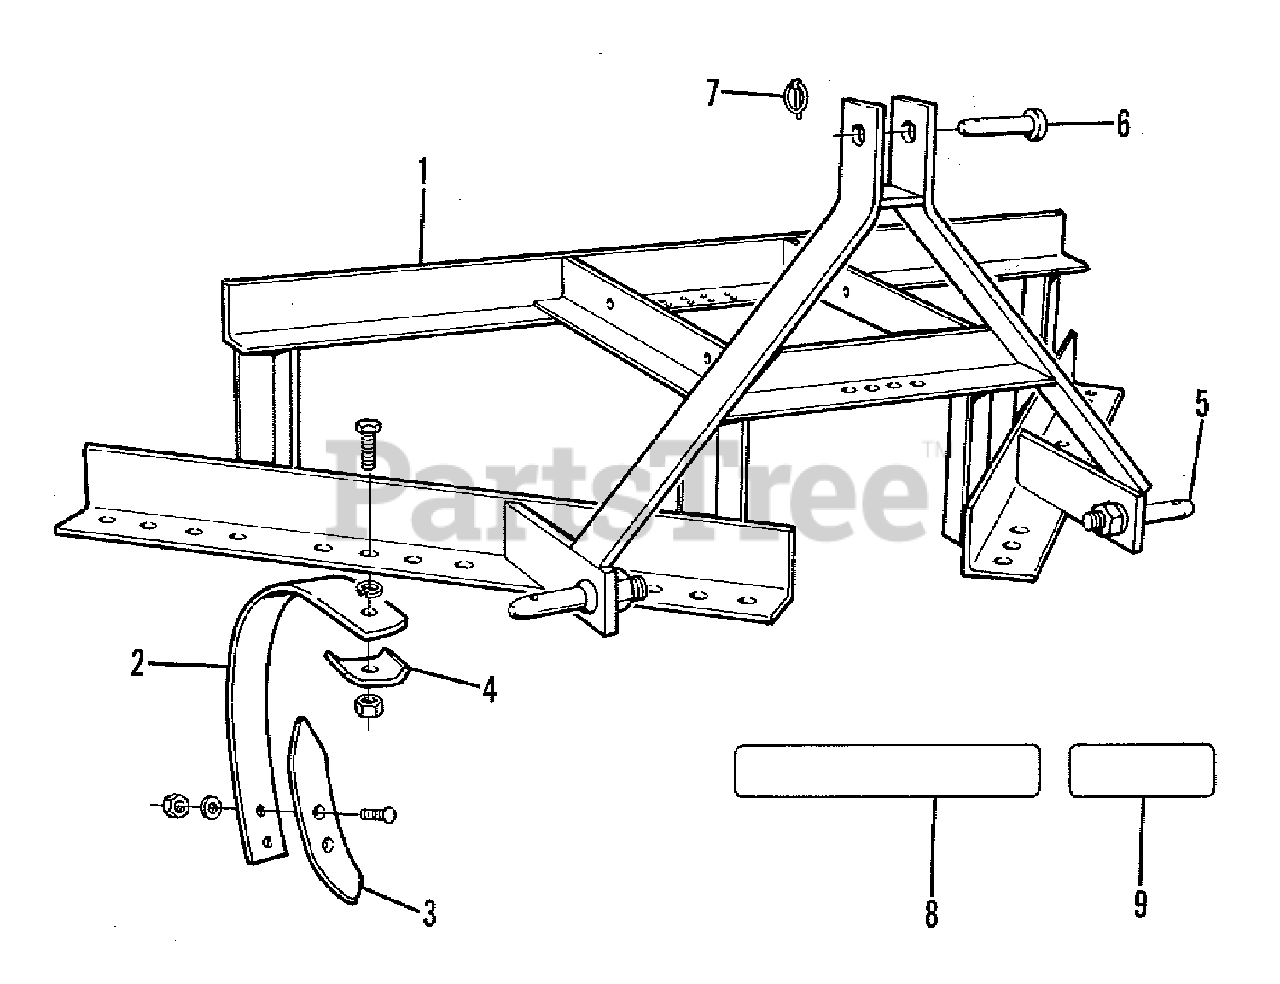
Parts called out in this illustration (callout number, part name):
1	FRAME ASSEMBLY
2	CAPSCREW, 5/8NC x 2
2	LOCKWASHER, 5/8
3	TOOTH, Double Pointed
3	BOLT, Plow, No. 3 Head, 3/8NC x 1-1/4
3	WASHER, Plain, 7/16 x 1 x 14 GA.
4	WASHER, Retaining
5	PIN, Link (Cat. 1)
5	LOCKWASHER, 7/8
6	PIN, Hitch, Upper
8	DECAL (Allis-Chalmers)
9	DECAL, (40 Model Identification)
